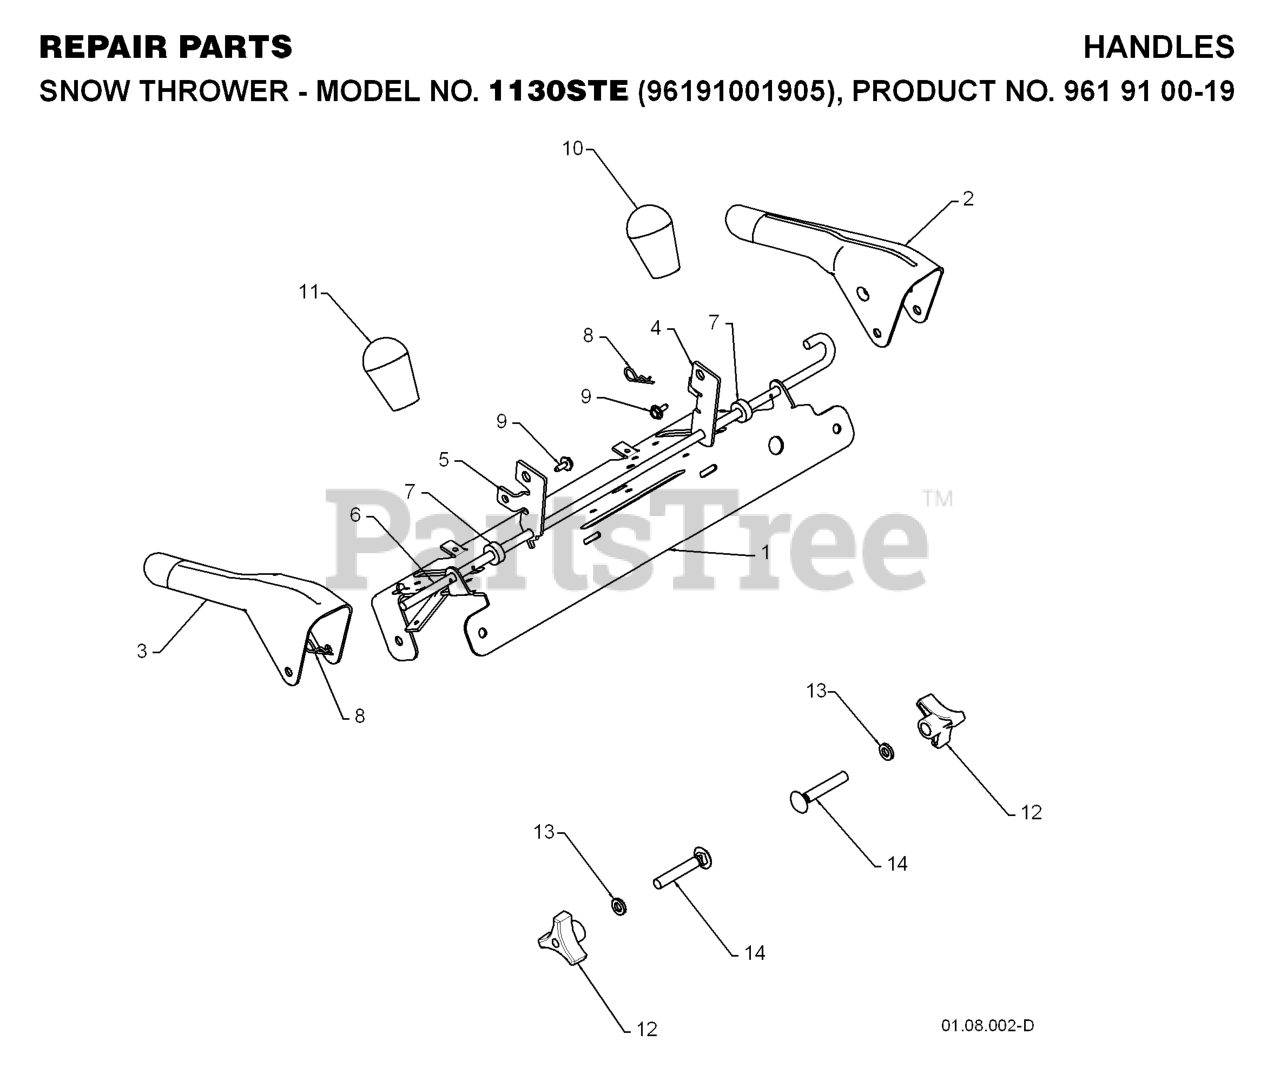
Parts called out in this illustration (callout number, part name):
1	PANEL.CONTROL.PNT.BLACK
2	LEVER.CONTROL.LH.PNT
3	LEVER.CONTROL.RH.PNT
4	ARM.TRACTION.ROD.YZ
5	ARM.IMPELLER.ROD.
6	BAIL.CONTROL.INTERLOCK
7	SPACER CONTROL LEVER
8	SPRING RETAINER
10	KNOB LEVER, BLACK
11	RED KNOB SHIFTER
12	KNOB.HANDLE.3/8.TRI-POINT.BLAC
13	WASHER
14	BOLT 3/8-16 X 2-1/4
